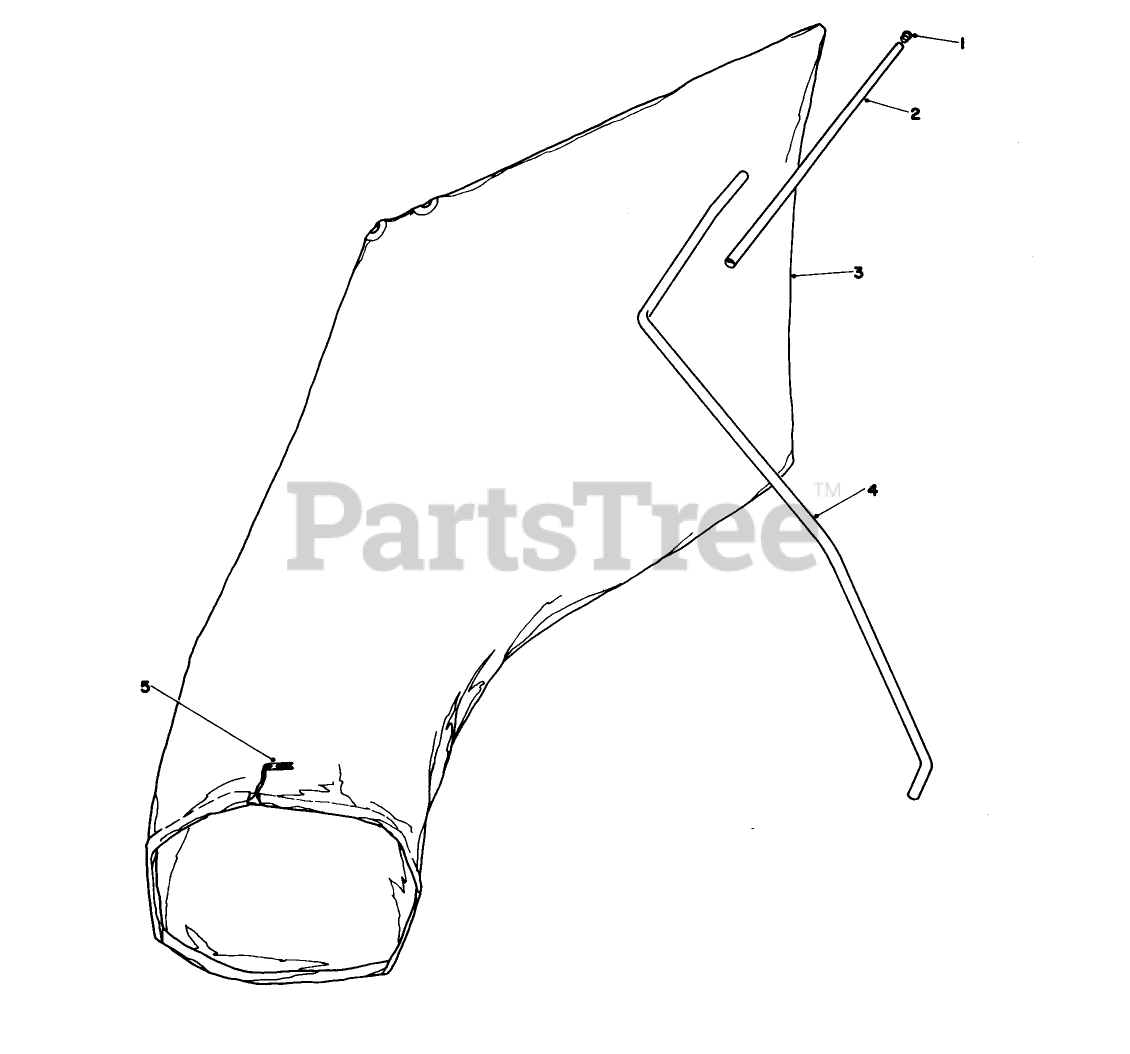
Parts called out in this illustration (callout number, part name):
2	BAG HANGER TUBE
4	HANGER ROD
5	BAG CORD FASTENER
